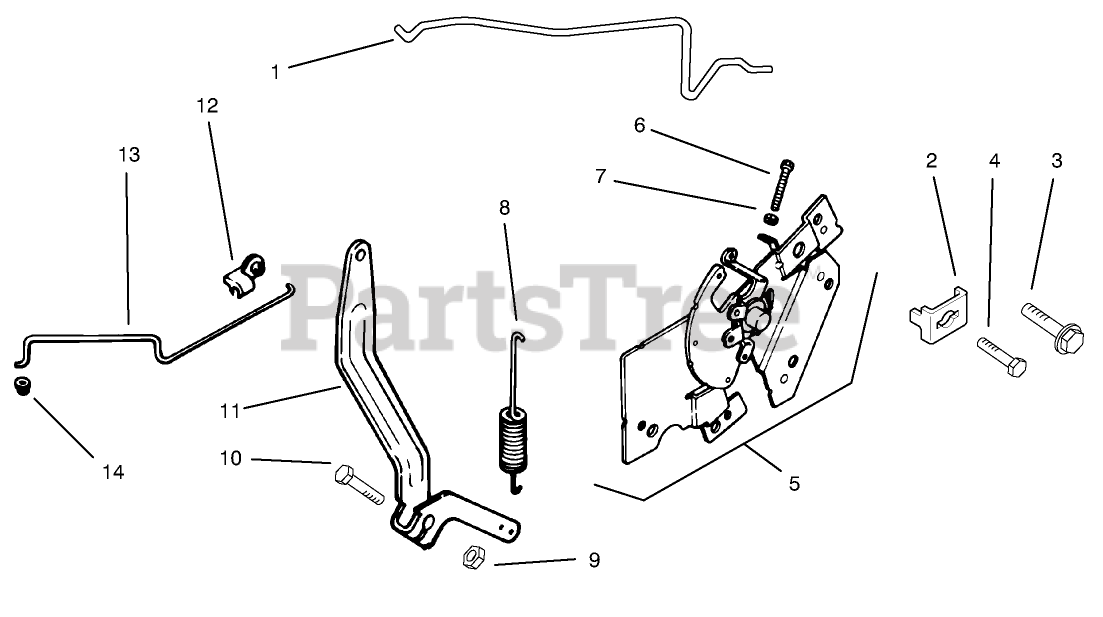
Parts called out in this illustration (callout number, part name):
1	Linkage-Choke (Only On: 72042,72043,72062,72063)
2	Clamp
3	Screw Socket
4	Screw M5x0.8x16 (Only On: 72042, 72063, 72062, 72043)
5	Control-ASM INC 6-7 (Only On: 72042, 72063, 72062, 72043)
6	Screw-HHF M4x0.7x28 (Only On: 72042, 72063, 72062, 72043)
7	Nut
8	Spring-Governor (Only On: 72042, 72063, 72062, 72043)
9	Nut
10	Screw
11	Lever-Governor (Only On: 72042, 72063, 72062, 72043)
12	Bushing-Linkage
13	Linkage-Throttle (Only On: 72042, 72063, 72062, 72043)
14	Bushing
